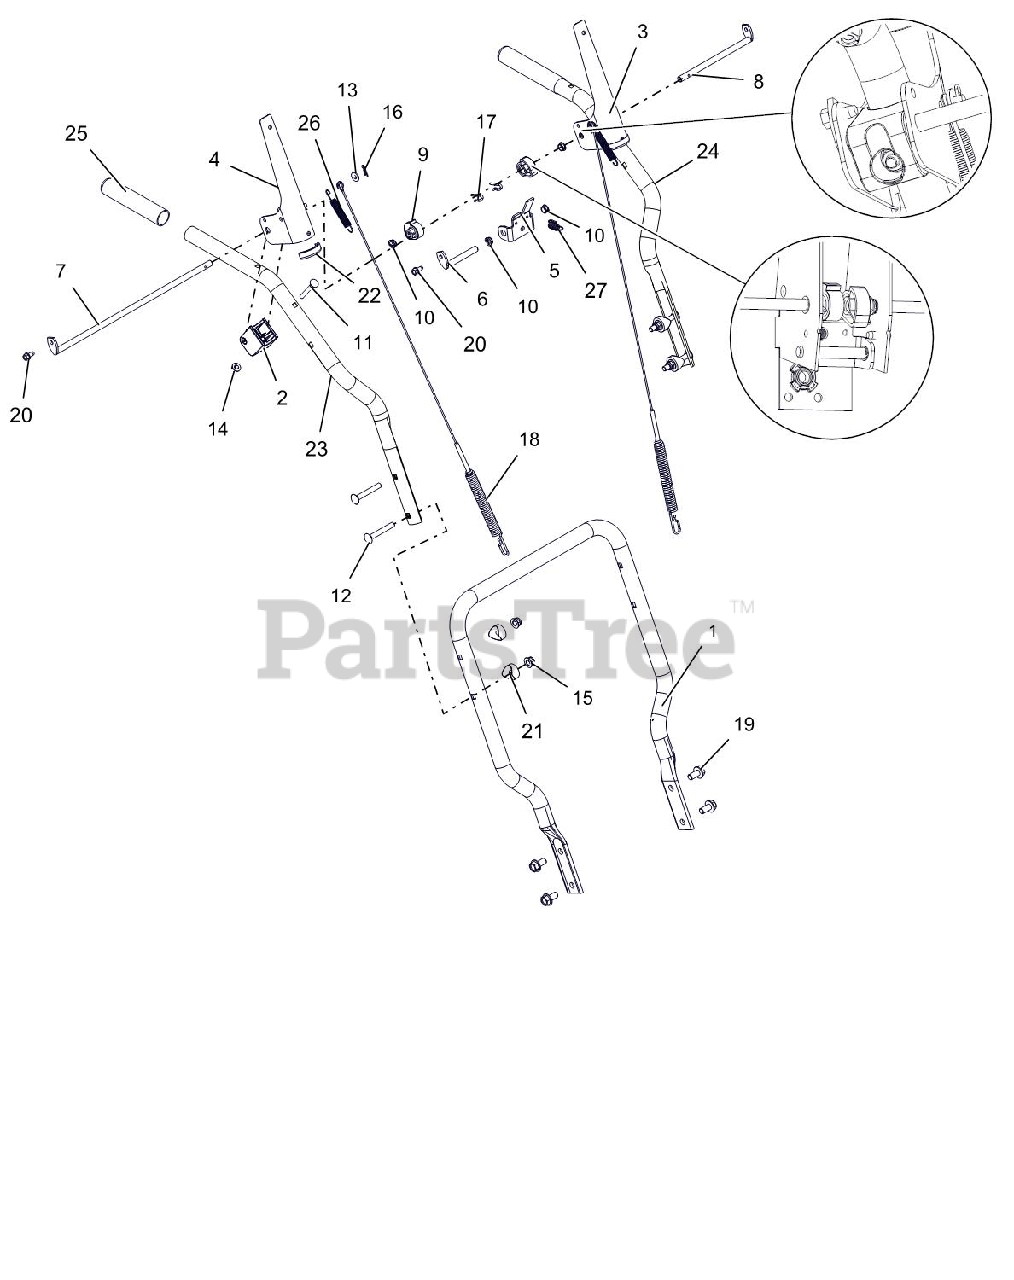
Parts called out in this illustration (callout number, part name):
1	HANDLEBAR, LOWER (COMPACT)
2	BLOCK, CLUTCH PADDLE
3	LEVER, CLUTCH-LH
4	LEVER, CLUTCH-RH
5	BRACKET, INTERLOCK ARM
6	ROD, PIVOT - INTERLOCK
7	ROD, PADDLE MOUNT - LONG
8	ROD, PADDLE MOUNT - SHORT
9	CAM, INTERLOCK
10	BUSHING, POLYLINER-.38 SNAPIN
11	BLT-RDHDXLSQNK .25-20X2.0 G5YZ
12	@BLT-RDHDSQNK .31-18X2.25 G5YZ
13	@WSHR-FL-STL.281X.62X.065 YWZC
14	@NUT-LK-TOP-FLG .25-20 YWZC
15	@NUT-LK-NYL-FLG .31-18 YWZC
16	PIN-HAIR INT .06X.18X.77
17	PIN, SPRING CLIP
18	CABLE, AUGER & UPPER TRACTION
19	BLT-SERHFWH .38-16X.75 YWZC
20	SCR-TAP .25-20X.50 HWH TR YWZ
21	SPACER, HANDLEBAR
22	EDGING, CLUTCH PADDLE - 2.00"
23	HANDLEBAR, UPPER - RH
24	HANDLEBAR, UPPER - LH
25	GRIP,HANDLE-GRAY
26	SPRING, EXTENSION
27	SPRING-EXT .047X.438X1.45
